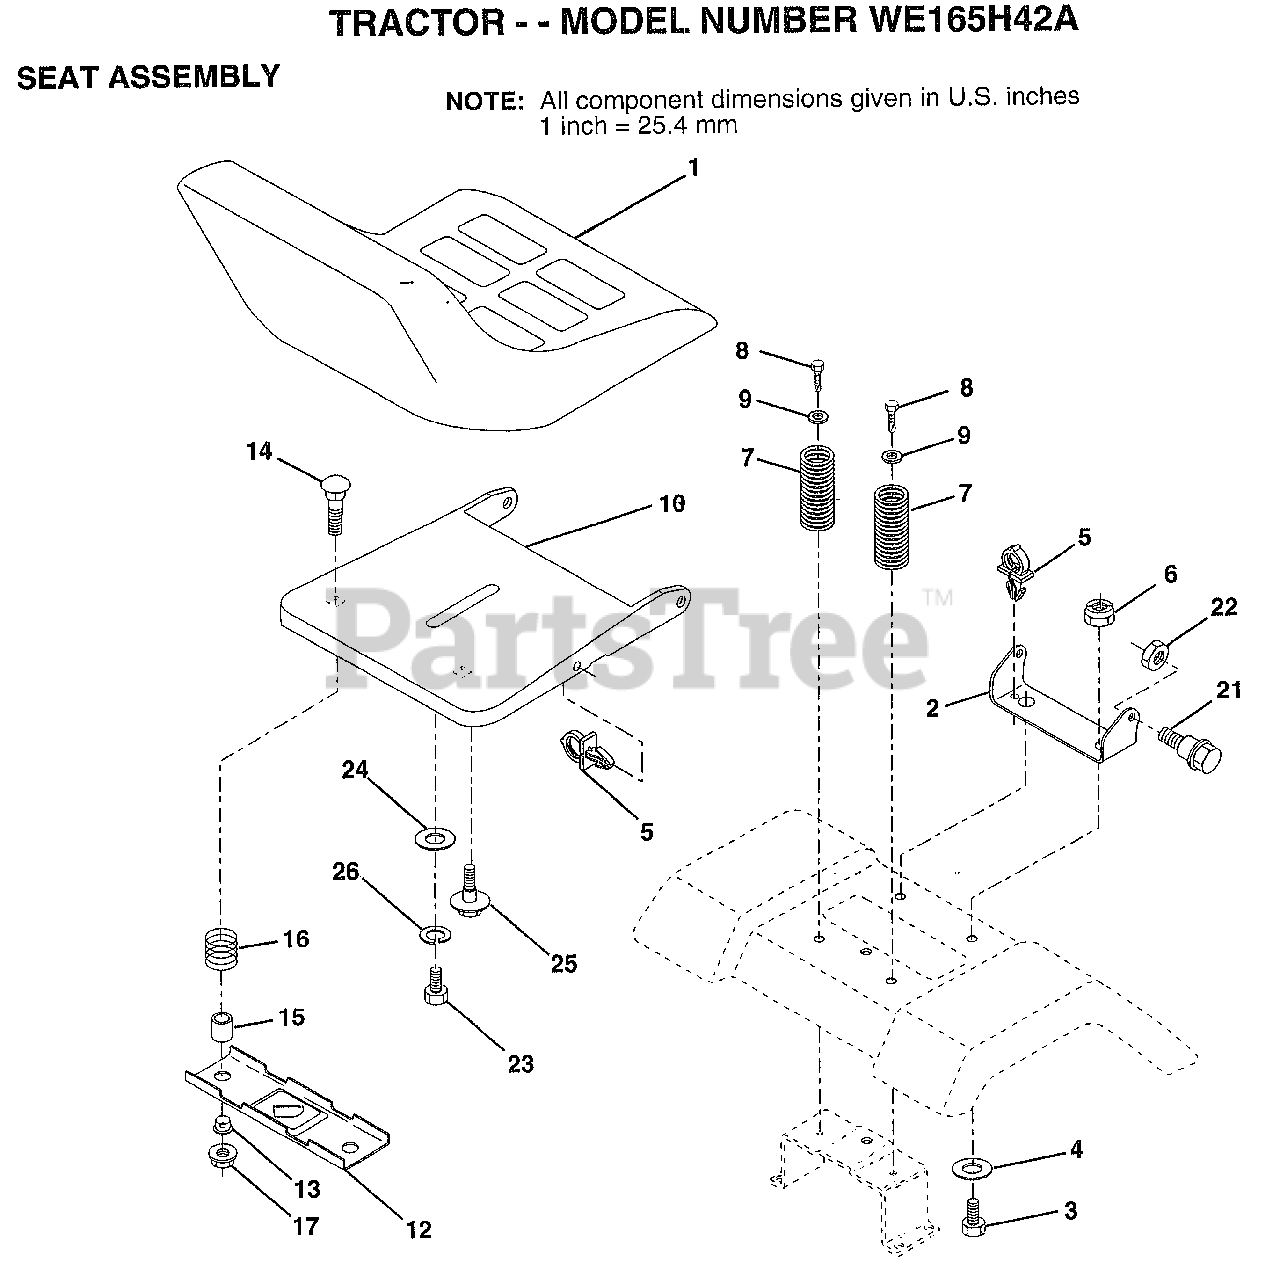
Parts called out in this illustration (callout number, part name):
2	BRACKET PVT SEAT
3	BOLT
4	WASHER PM
5	CLIP.PUSH-IN.HING
6	NUT
7	SPRING COMPRESSIO
8	SCREW GTV
9	WASHER
10	PAN-SEAT
12	BRKT SWITCH
13	BUSHING
14	BOLT-RD HD SQ NK
15	SPLIT SPACER
16	SPRING
21	"BOLT,SHOULDER"
22	NUT
23	BOLT
24	WASHER
25	"BOLT,SHOULDER"
26	LOCKWASHER
